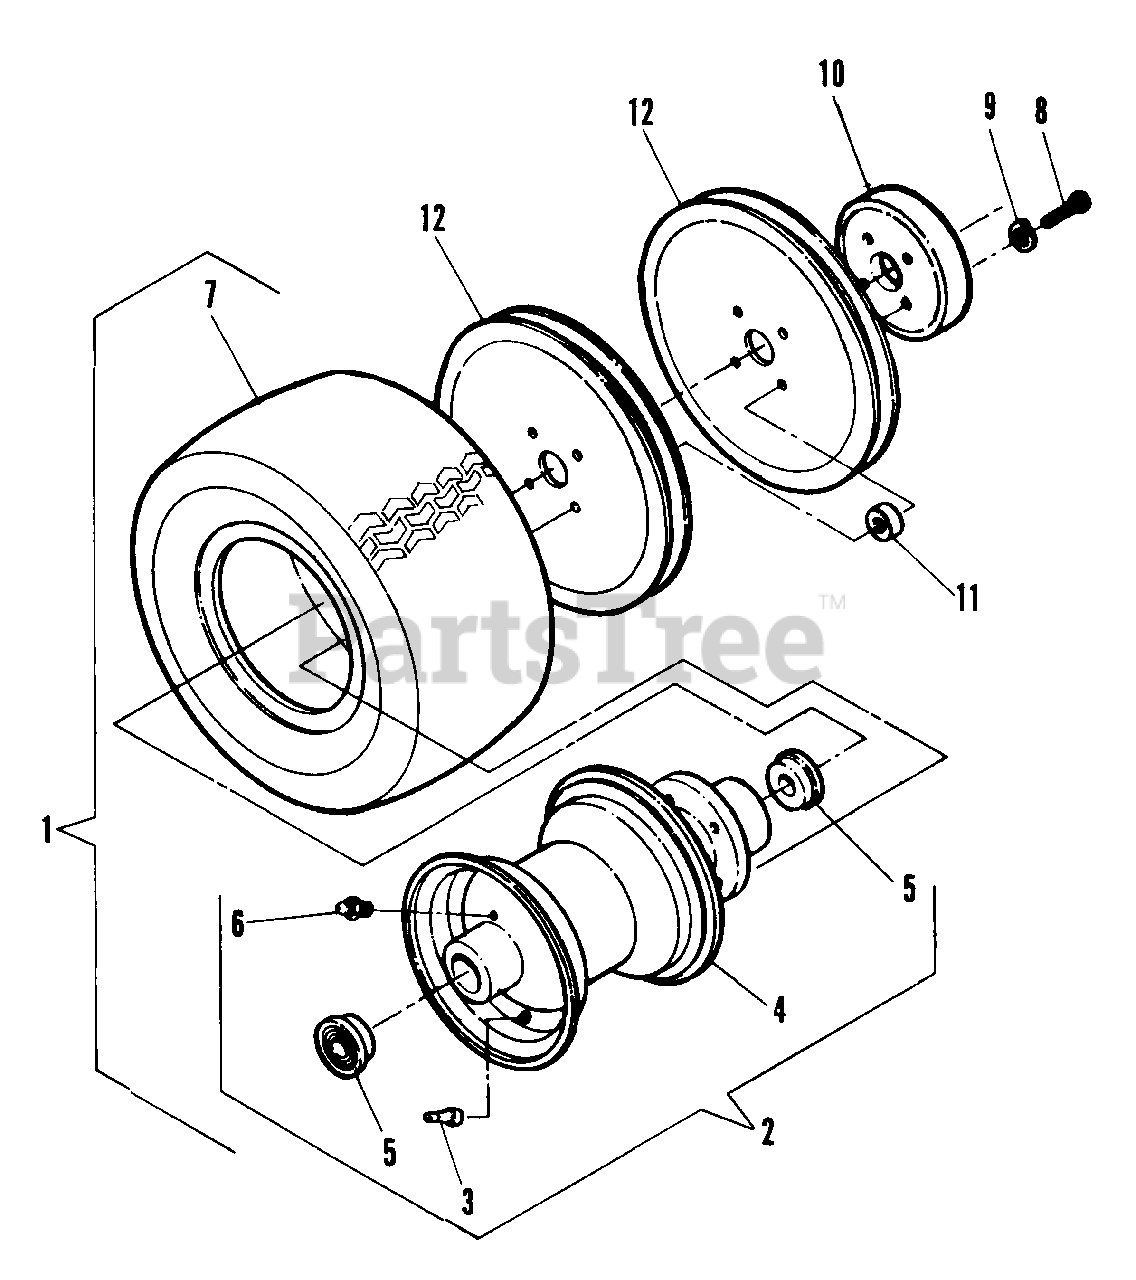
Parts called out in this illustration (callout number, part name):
1	WHEEL & RIM ASSEMBLY
2	RIM ASSEMBLY
3	VALVE STEM
4	RIM
5	BEARING, Wheel
6	ZERK FITTING
7	TIRE, 6.50 x 13-6, 4 Ply, Tubeless
8	SCREW, Hex Head Cap, 5/16"-24 x 1 1/2
9	WASHER, Lock, 5/16"
10	DRUM, Brake
11	SPACER
12	PULLEY, 9"
